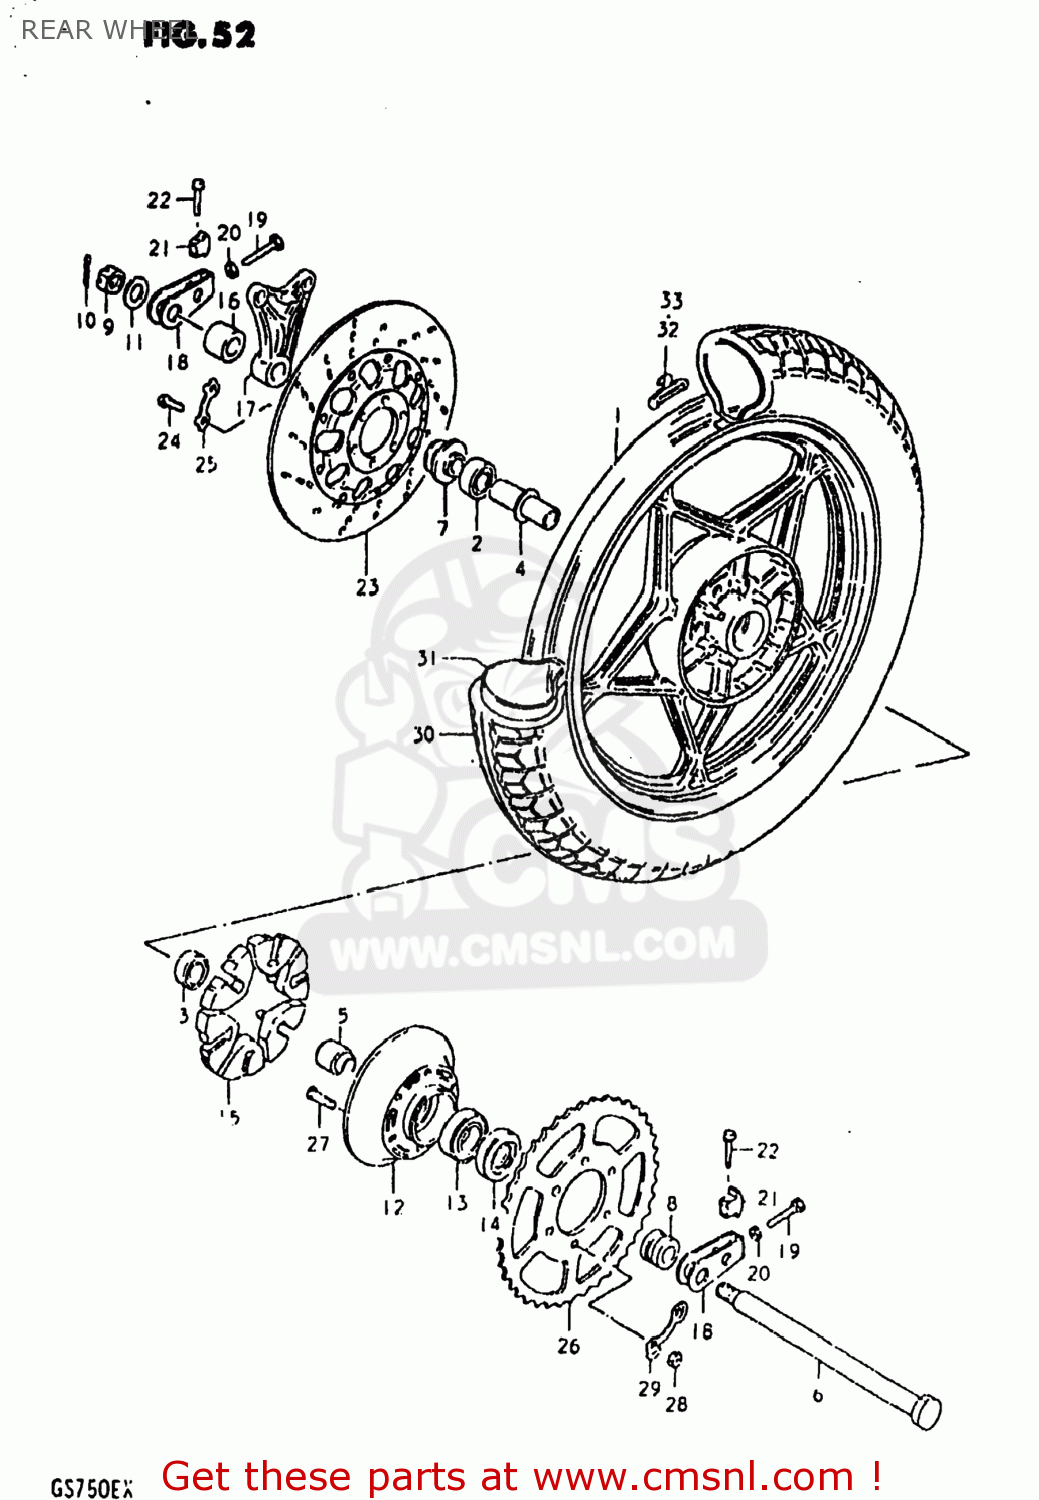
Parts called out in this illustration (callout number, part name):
1	WHEEL, REAR
2	BEARING WHEEL REAR(20X47X14)
3	BEARING, LH
4	SPACER,REAR HUB BEARING
5	SPACER,REAR HUB BEARING
6	AXLE,REAR
7	SPACER,REAR AXLE
8	SPACER(20X33X28.3)
9	NUT 18MM
10	PIN,COTTER
11	WASHER(19X34X4)
12	DRUM,REAR SPROCKET MOUNT
13	BEARING
14	SEAL,OIL(33X62X7)
15	ABSORBER,REAR HUB SHOCK
16	SPACER (20X38X17)
17	BRACKET,RR,CALIPER
18	ADJUSTER,CHAIN
19	BOLT
20	NUT
21	SUPPORTER,CHAIN ADJUST
22	BOLT (8X40)
23	DISC,RR BRAKE
24	BOLT(8X30)
25	WASHER
26	SPROCKET,RR
27	BOLT
28	NUT
29	WASHER
30	TIRE
31	TUBE ASSEMBLY,WHEEL,INNER
32	BALANCER,WHEEL
33	BALANCER,WHEEL
